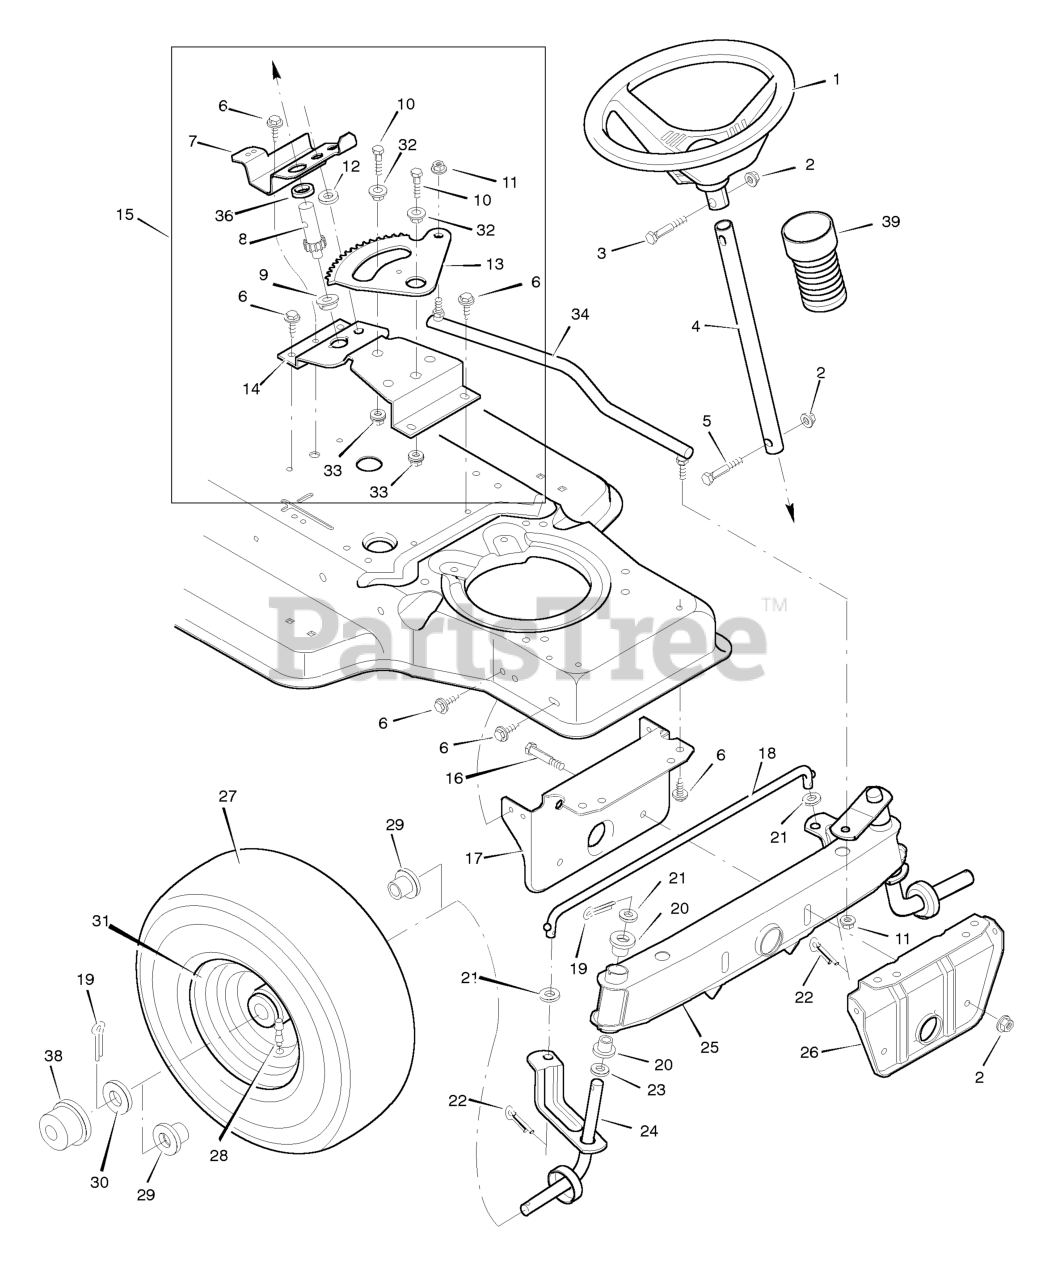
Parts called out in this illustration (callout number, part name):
1	Wheel, Steering
2	Nut, Hex
3	Bolt, Hex
4	Post, Steering
5	Bolt, Hex
7	Bracket, Sector
8	Gear, Pinion
9	Bearing
10	CAPSCREW, Hex Head, 5/16-18 x 1
11	Locknut, Flange
13	Gear, Sector
14	Bracket, Sector
15	Kit, Steering Gear
16	Bolt, Hex
17	Support, Rear Axle
18	Rod, Tie
19	Pin, Cotter
20	Bearing
22	Pin, Cotter
24	Spindle Assembly, Right
25	Spindle Assembly, Axle & Left
26	Support, Front Axle
27	Tire *
28	Stem, Valve
29	Bearing, Wheel
31	Wheel & Tire Assembly
32	Bearing
33	Locknut, Flange
34	Link, Drag
36	Spacer, Pinion Gear
38	Hub Cap
39	Bellows
